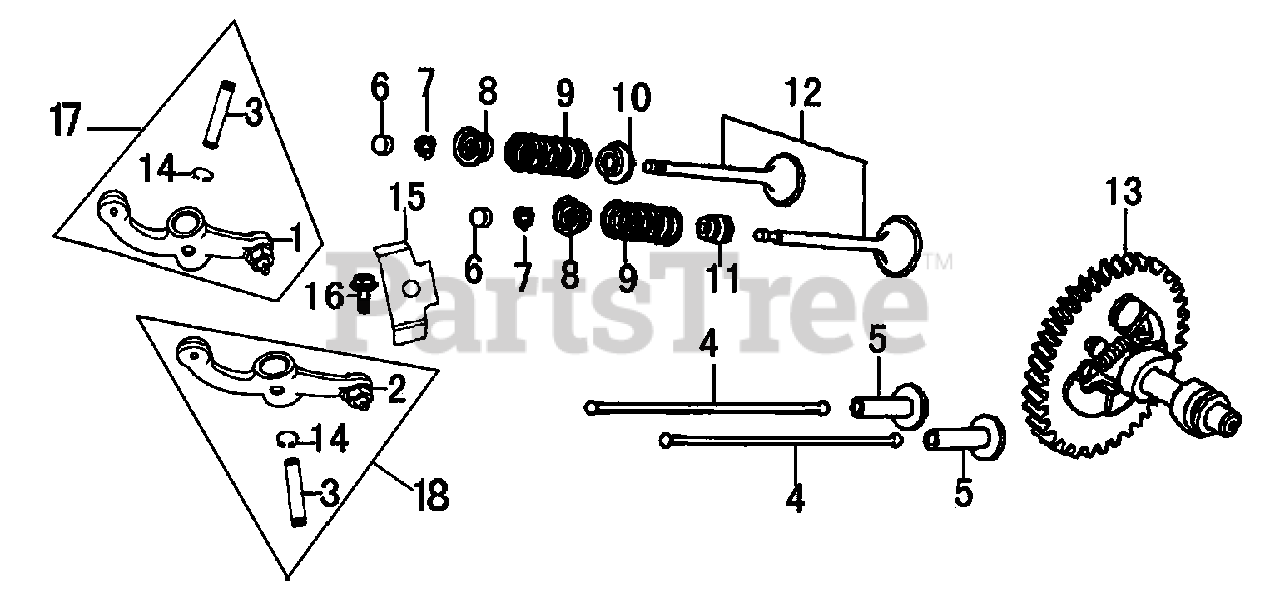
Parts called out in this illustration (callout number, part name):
1	ROCKER ARM ASSY. EXH.
2	ROCKER ARM ASSY. INT.
3	VALVE ROCKER SHAFT
5	LIFTER, VALVE
6	ROTATOR, VALVE
7	LOCKER, VALVE
8	RETAINER, VALVE SPRING
9	SPRING, VALVE
10	SEAT, VALVE SPRING
11	SEAL, VALVE STEM
12	VALVE ASSY.
13	CAMSHAFT ASSY
15	RETAINER, ROCKER ARM SHAFT
16	BOLT, FLANGE
17	ROCKER ARM ASSY. EXHAUST
18	ROCKER ARM ASSY. INTAKE
